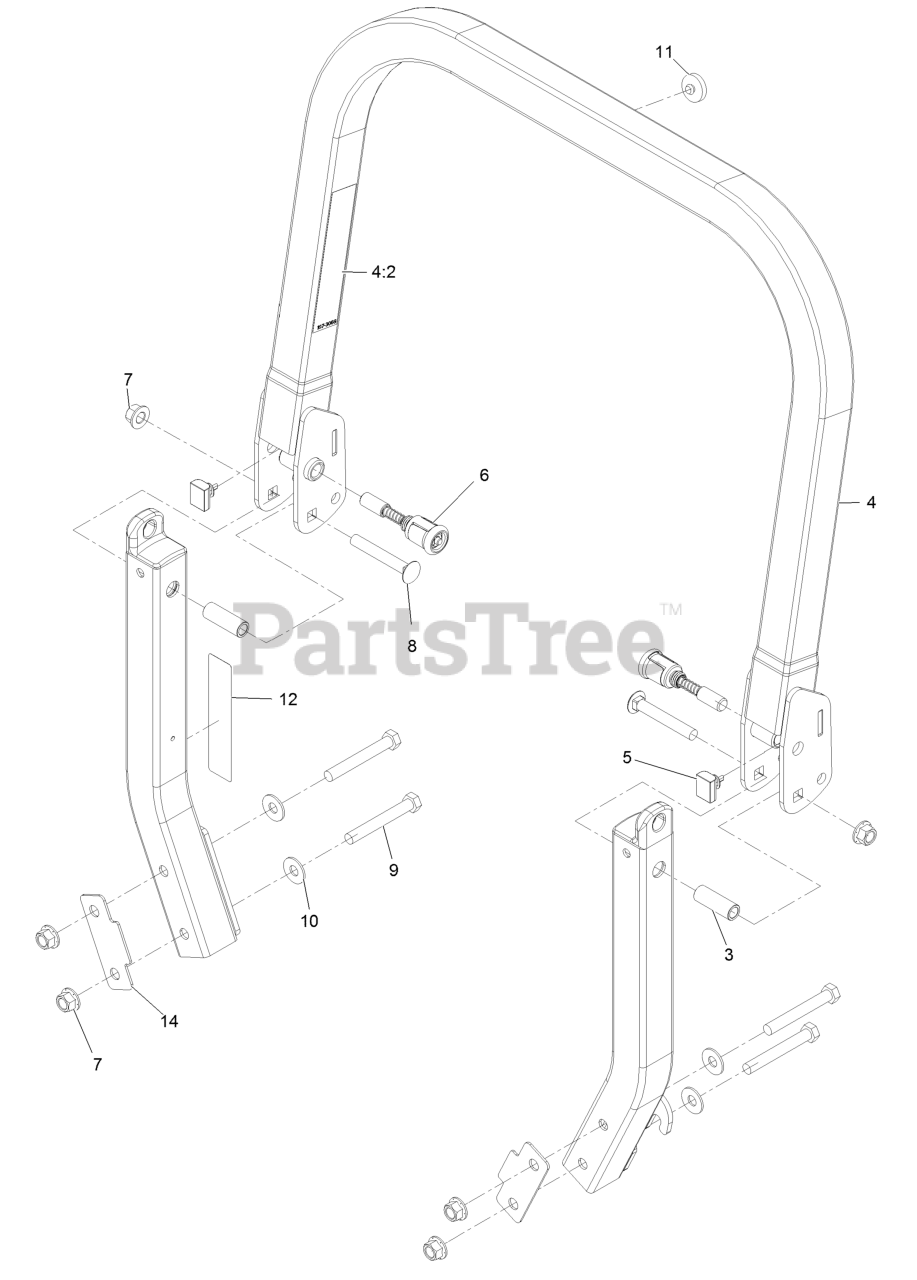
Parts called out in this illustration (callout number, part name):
4	UPPER ROPS ASM
4:2	DECAL-WARNING
5	BUMPER-ROPS
6	PIN-SPRING
7	Nut-Lock 1/2-13
8	SCREW-CARR
9	WASHER-LOCK
10	WASHER-SPRING
11	BUMPER-PUSH-IN, RUBBER
12	DECAL-CAUTION, FUEL VENT
